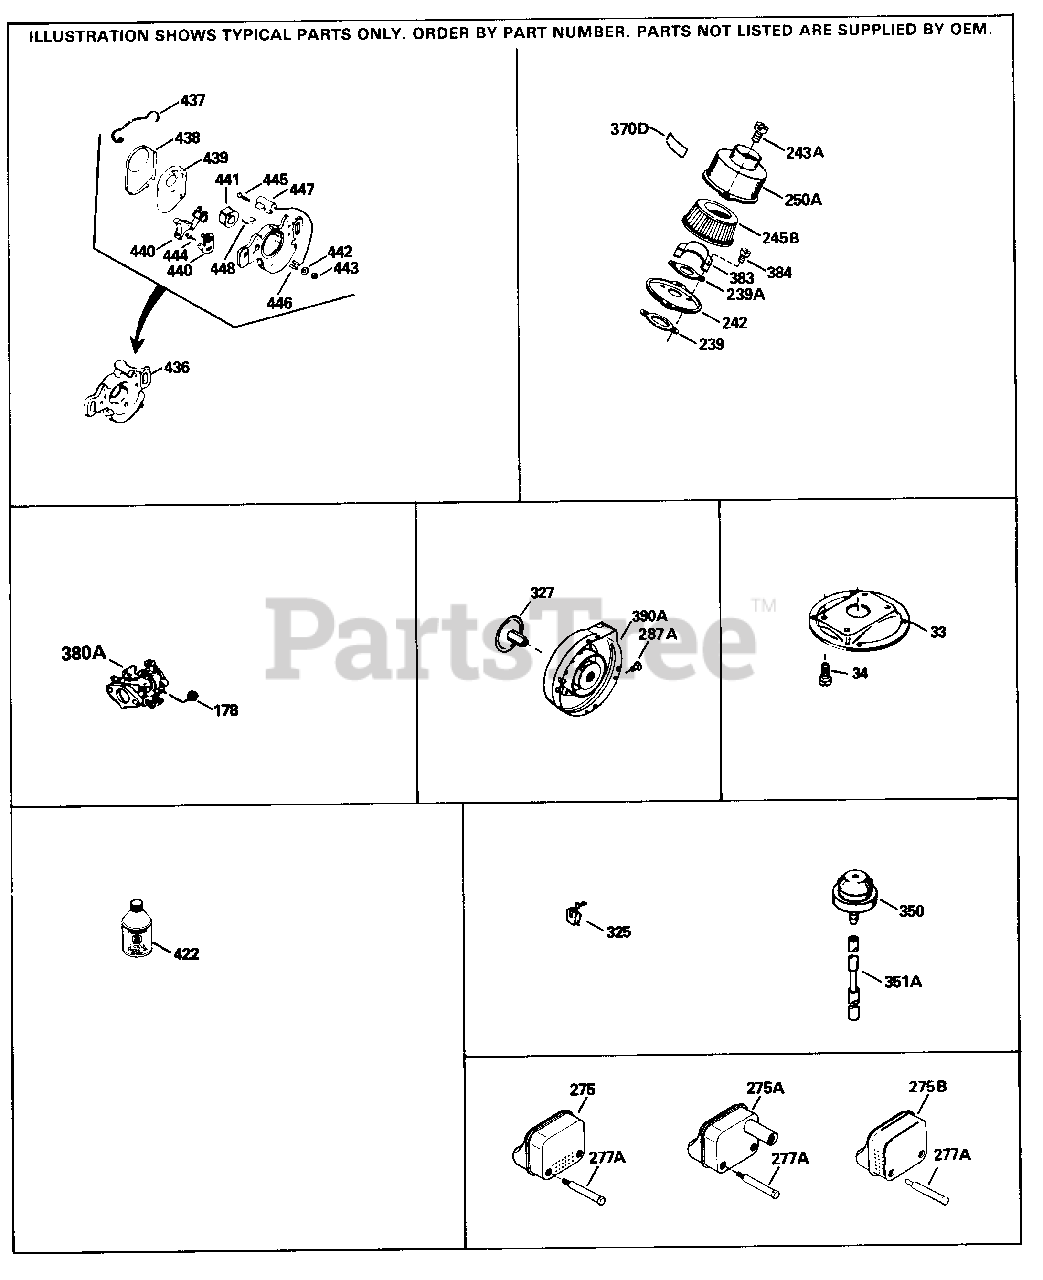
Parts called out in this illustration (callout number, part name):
178	Nut & Lock Washer 1/4-28
350	Primer Bulb
422	2-Cycle Oil with Fuel Stabilizer - 8 oz.
